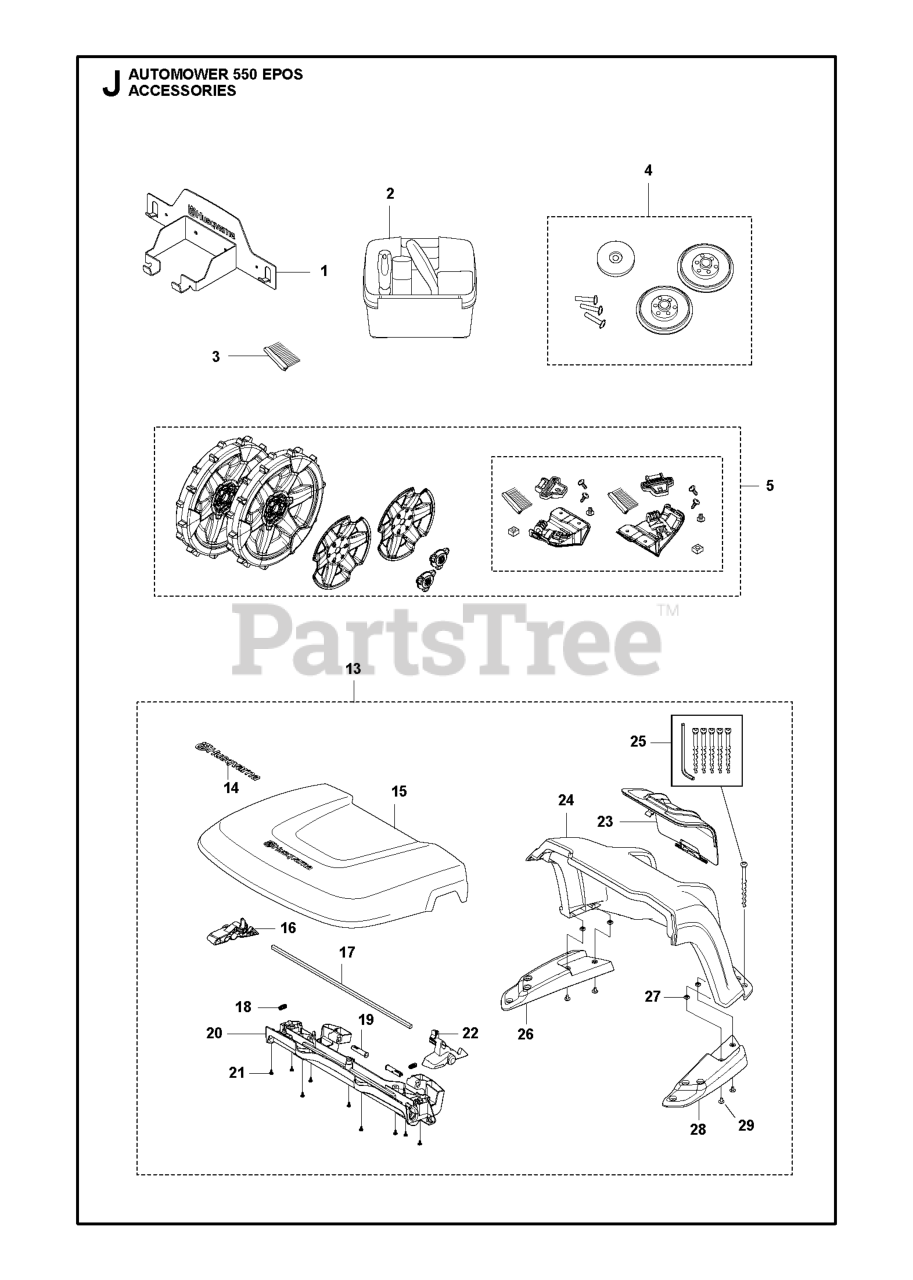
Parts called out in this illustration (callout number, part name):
1	MISC. BLISTER WALL HANGER
2	CLEANING AND MAITENANCE KIT AM
3	WHEEL BRUSH REFILL KIT
5	REAR WHEEL KIT W/ BRUSHES
13	430/450 HOUSE KIT
13	COVER
14	DECAL.HUSQVARNA.210MM
15	KIT LID - AUTOMOWER HOUSE
16	HANDLE RELEASE LEFT
17	ROD
18	SPRING SPRING CAP
19	HINGE PIN
20	BEAM
21	SCREW 14MM
22	HANDLE RELEASE RIGHT
23	HATCH
24	COVER BASE P2 HOUSE
25	Screws
26	SUPPORT BASE LEFT
27	NUT
28	SUPPORT BASE RIGHT
29	SCREW IHPANM M6X25 4.6 ZP-BC
